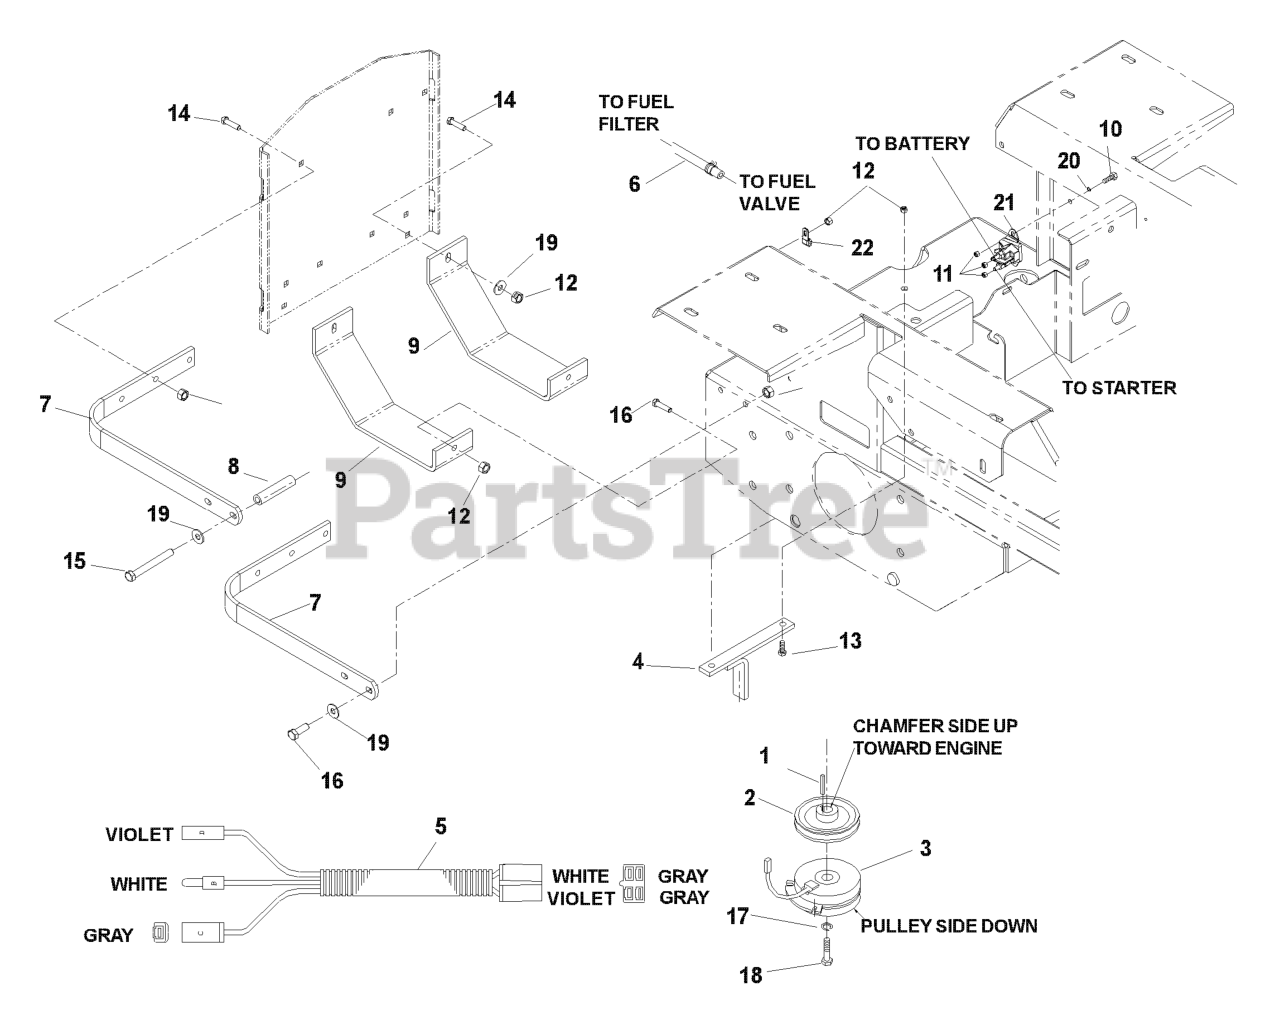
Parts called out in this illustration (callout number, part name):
1	KEY, 1/4 SQ X 1 1/4
3	CLUTCH-200 FT LB(RPLS 5218-102
4	CLUTCH TIE DOWN
5	KAW PIGTAIL
6	FUEL LINE 29.5"
7	ENGINE SHROUD BRKT
9	SKID PLATE
10	HCS 1/4C X 5/8
11	NUT.1/4-20.HEX.NYLOC.ZD
12	NUT 5/16 NYLOC
13	HCS 5/16C X 1 3/4
14	RHSSNB 5/16C X 1.0
15	HCS 5/16C X 4
16	HCS 5/16C X 1
17	WASHER 7/16 LOCK
18	BOLT 7/16F X 2 1/2
19	WASHER 5/16 FLAT
20	WASHER 1/4 INT TOOTH
22	DOUBLE TUBE CLAMP
